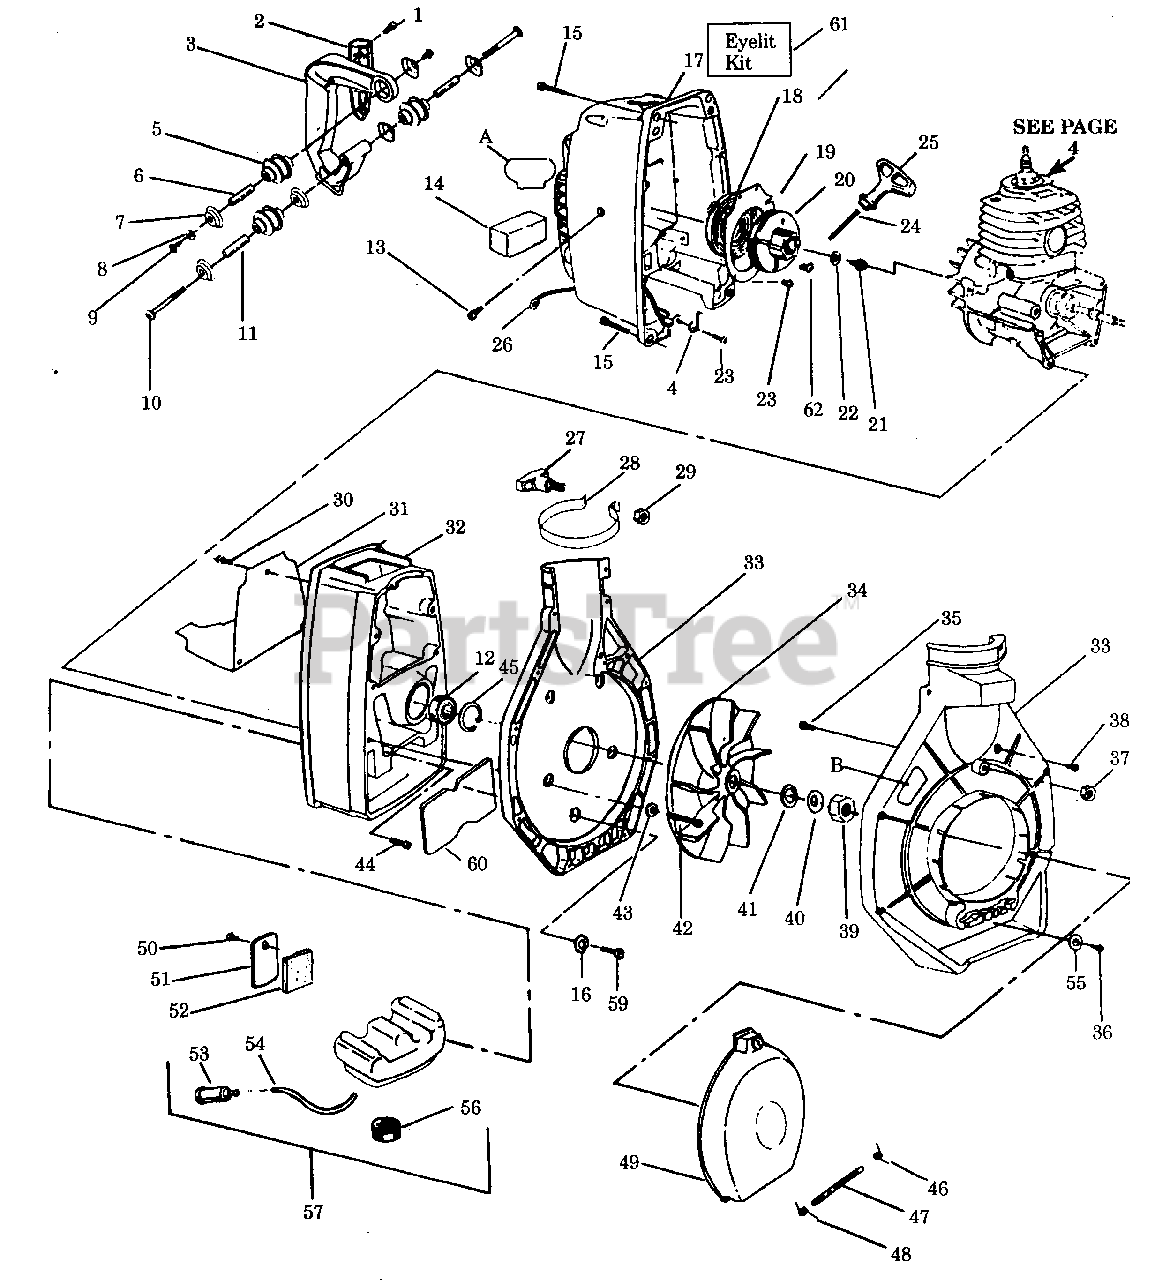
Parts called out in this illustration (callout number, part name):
2	Handle Cover
3	Handle Ass'y.
4	Static Ground Wire Model 920,925,960
5	Handle Isolator
6	Isolator Spacer (Front)
7	Isolator Cup
11	Isolator Spacer (Rear)
12	Ball Bearing (Shroud) See Service Ref. 1
14	Air Filter
17	Fan Housing
18	Starter Pulley Spring
19	Air Baffle
21	Screw
24	Rope Kit
25	Starter Rope Handle
26	Ground Wire Model 920,925,960
27	"T" Handle Kit
28	Blower Tube Clamp
31	Heat Deflector
32	Shroud
33	Blower Hsg. Ass'y. (Incl. #36,46-49 & 55, & Key No. 5 of Vac Attachment Kit)
34	Impeller
36	Screw
38	Screw
41	Washer
43	Washer
45	Shroud Bearing Retainer
46	Spring-Tension (Right)
47	Pivot Pin
48	Spring-Tension (Left)
49	Inlet Door Ass'y.
51	Fuel Tank Retainer
52	Fuel Tank Cushion
53	Fuel Pick-Up Ass'y
54	Line Kit
56	Fuel Cap Ass'y.
57	Fuel Tank Ass'y.
60	Fuel Tank Shield
61	Eylet Kit
62	Screw
A	Instruction Decal
B	Blower/Vac Warning Decal
